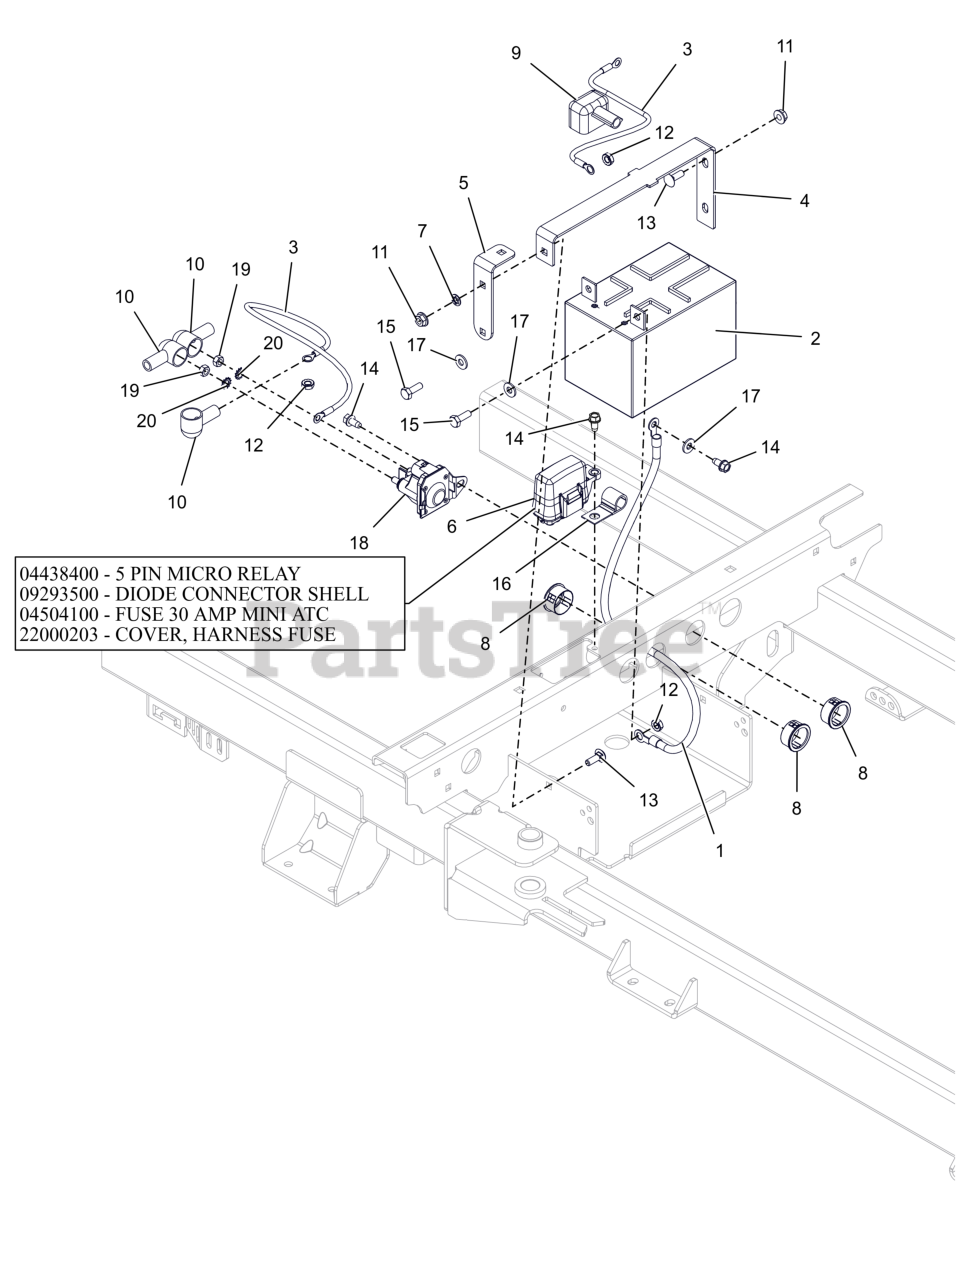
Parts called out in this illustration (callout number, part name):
1	CABLE-NEGATIVE BATTERY 24.00"
2	BATTERY, 12V 12A-190CCA
3	CABLE,POS W/2 1/4 RING 15.0 LG
4	BRKT, BATTERY HOLD-DOWN
5	BRKT, BATTERY HOLD DOWN
6	HARNESS, WIRE-4POS KEY IKON/ZT
6	RELAY,MICRO5 TERML W/RESISTOR
6	DIODE, CONNECTOR SHELL
6	FUSE,30 AMP MINI-ATC
6	COVER, FUSE
7	NUT-PUSH .25X.50 O.D.
8	BSHG, PANEL SNAP .937X1.11X.56
9	INSULATOR
10	BOOT, EYELET TERMINAL
11	NUT-LK-TOP-FLG .250-20 GF ZCC
12	NUT-KEPS .250-20 ZCC
13	BLT, RHSN .25-20X.750 G5 ZCC
14	SCR-TAP .25-20X.50 HWH ZCC
15	BLT, HEX .25-20X.75 G5 ZCC
17	WSHR,FLT .281X.625X.065 ZCC
18	SOLENOID, STARTER (SEALED)
19	NUT-STD M6-1.0 ZCC
20	WSHR,LK-EXT.262X.502X.026 ZCC
